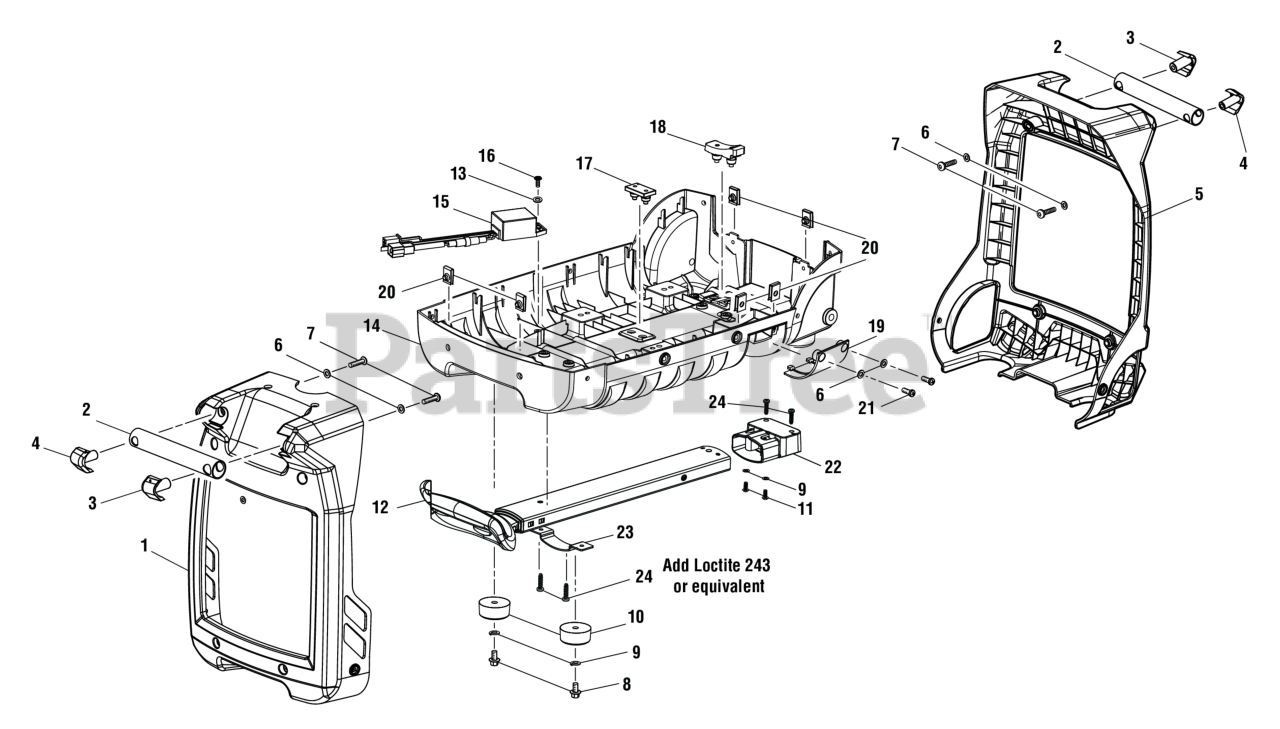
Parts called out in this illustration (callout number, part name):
1	Front Cover
2	Handle Tube
3	Handle Cap (Right)
4	Handle Cap (Left)
5	Rear Panel
6	Washer (ID5.3 x OD10 x 1t)
7	Screw (M5 x 20 mm, Button Soc. Hd.)
8	Bolt (M6 x 12 mm, Hex Hd.)
9	Lock Washer (1/4 in.)
10	Isolator Foot
11	Screw (M5 x 12 mm, T25 Torx Pan Hd.)
12	Retractable Handle Assembly
13	Washer (ID5.3 x OD10 x 1t)
14	Bottom Base
15	Regulator (AC to DC)
16	Screw (M4 x 16 mm, T15 Torx Pan Hd.)
17	Engine Support Isolator (Front)
18	Engine Support Isolator (Back)
19	Oil Drain Door
20	U-Clip (M5)
21	Screw (M5 x 12 mm, Phillips Pan Hd)
22	Handle Bracket (Plastic)
23	Metal Bracket
24	Screw (M4.2 x 15 mm, Phillips Hd. S.T.)
